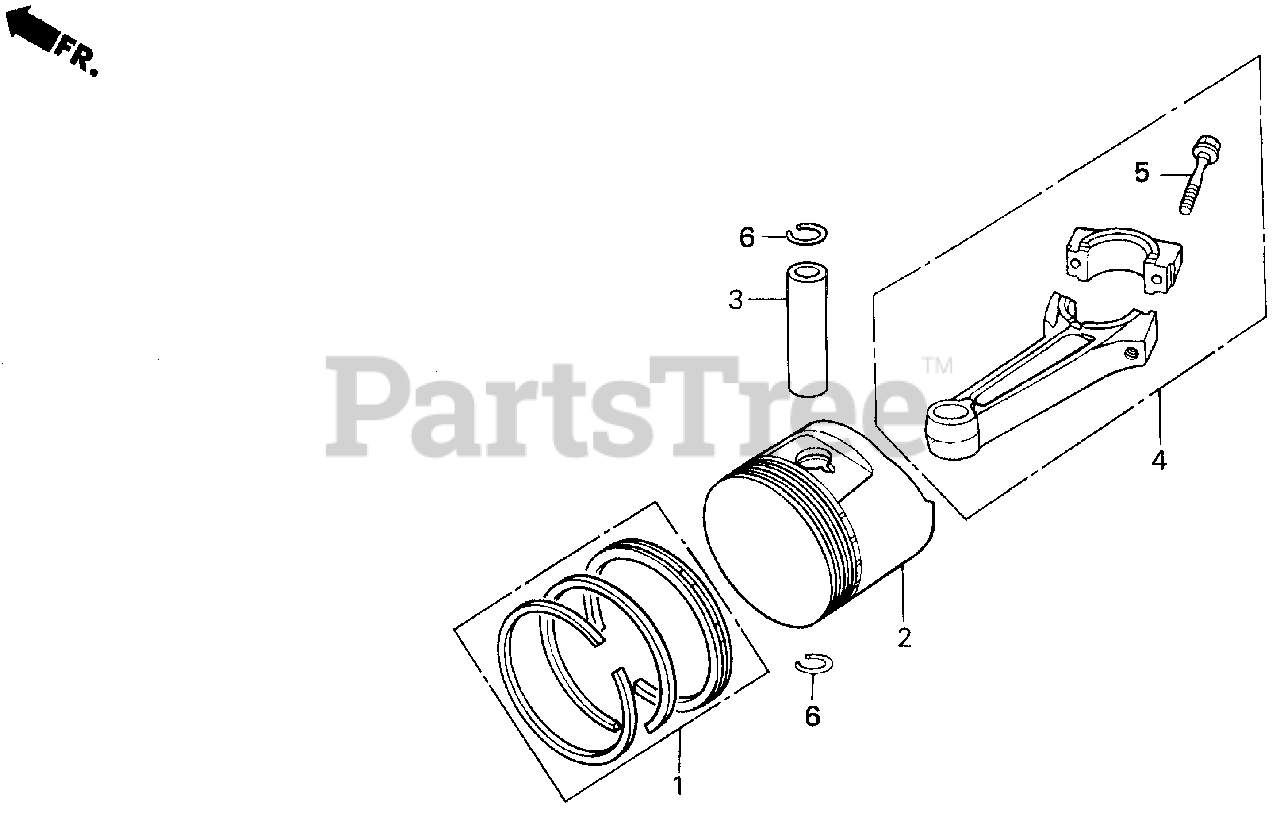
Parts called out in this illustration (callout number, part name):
1	RING SET, PISTON (STD)
1	RING SET, PISTON (OS 0.25)
1	RING SET, PISTON (OS 0.50)
2	PISTON (STD)
2	PISTON (OS 0.25)
2	PISTON (OS 0.50)
3	PIN, PISTON
4	ROD ASSY., CONNECTING
4	ROD ASSY., CONNECTING (Honda Code 2953107). (US 0.25)
5	BOLT, CONNECTING ROD
6	CLIP, PISTON PIN (20MM)
